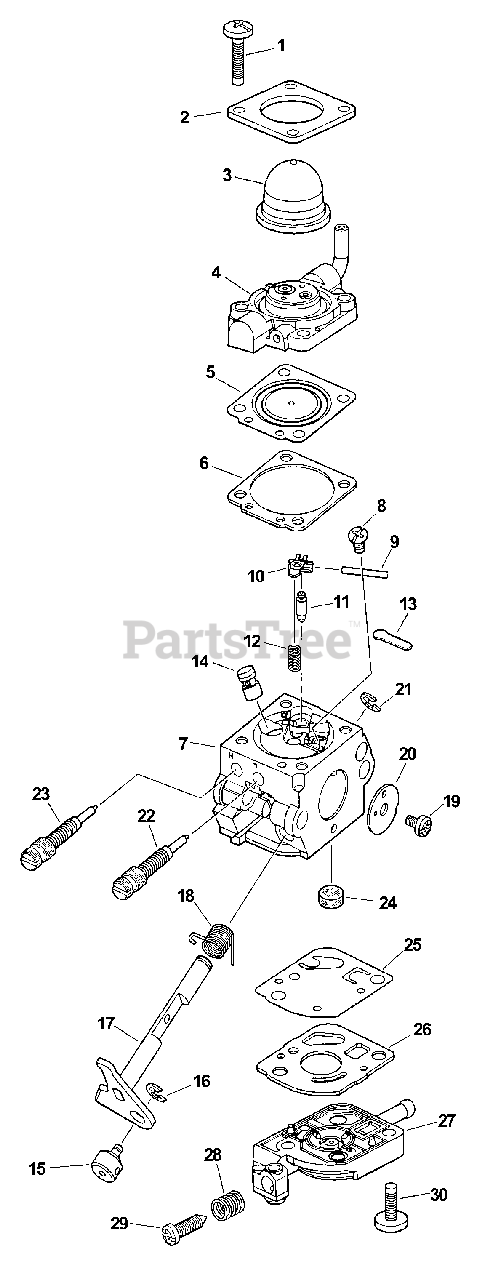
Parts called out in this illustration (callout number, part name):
1	SCREW
2	RETAINER, PURGE BULB
3	BULB, PURGE
4	BODY ASSY, PURGE
5	DIAPHRAGM, METERING
6	GASKET, METERING
7	BODY, CARBURETOR
8	SCREW
9	PIN, METERING LEVER
10	LEVER, METERING
11	VALVE, INLET NEEDLE
12	SPRING, METERING LEVER
13	PLUG, WELCH
14	NOZZLE, CHECK VALVE
17	SHAFT, THROTTLE
18	SPRING, THROTTLE RETURN
20	VALVE, THROTTLE
22	NEEDLE, MIXTURE
23	NEEDLE, HIGH SPEED
24	STRAINER
27	COVER, FUEL PUMP
29	SCREW, THROTTLE ADJUST
